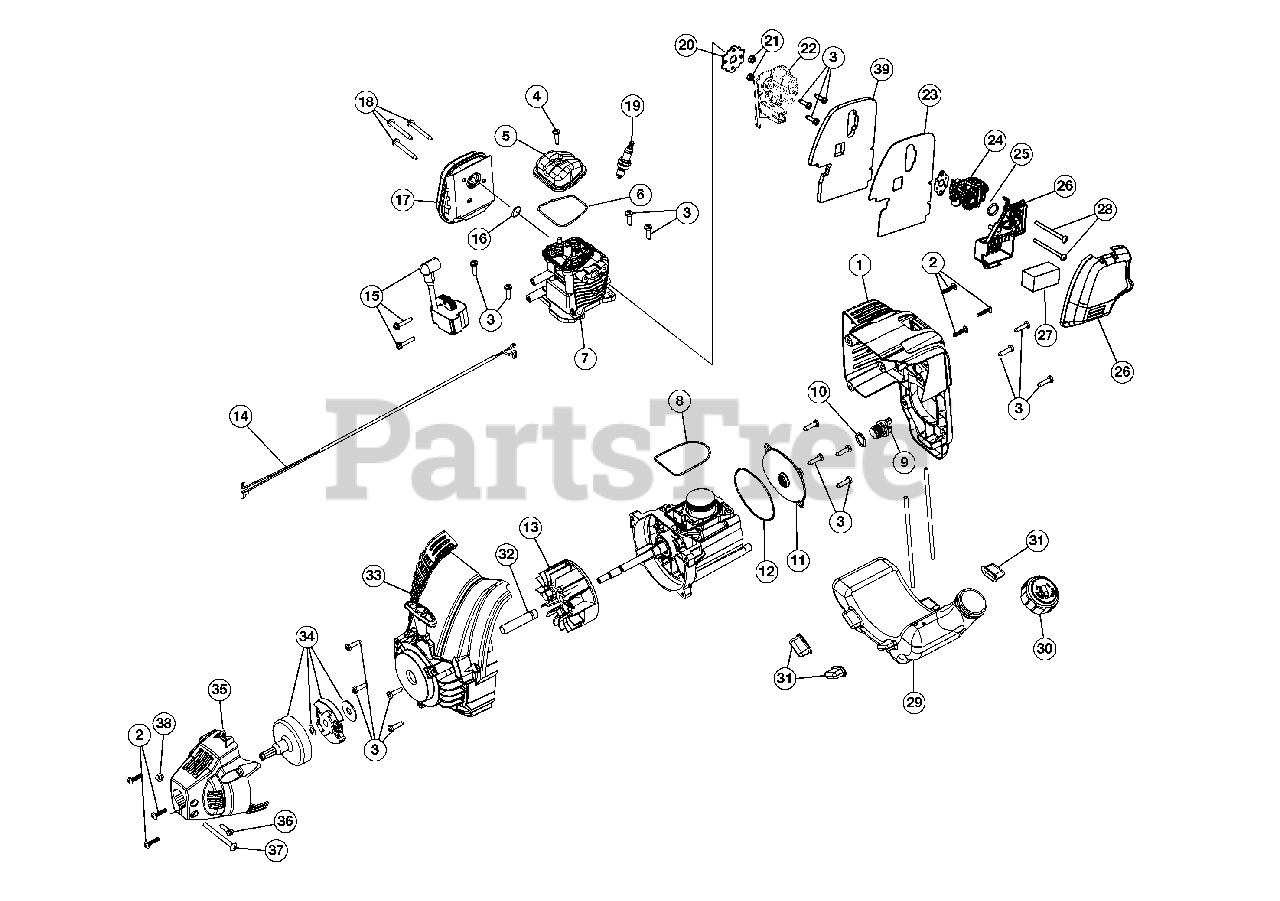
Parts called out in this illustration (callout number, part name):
1	Engine Cover Assembly (Incl. 2 & 3)
2	Cover Screw
3	Housing Screw
4	Rocker Cover Screw
5	Rocker Cover
6	Rocker Cover O-Ring
7	Cylinder Assembly (Incl. 3 - 6 & 8)
8	Cylinder O-Ring
9	Oil Plug (Incl. 10)
10	Oil Plug O-Ring
11	Crankcase Cover
12	Crankcase Cover O-Ring
13	Flywheel Assembly
14	Lead Wires
15	Module Assembly
16	Muffler Gasket
17	Muffler Assembly (Incl. 16 & 18)
18	Muffler Screw
19	Spark Plug
20	Insulator Gasket
23	Carburetor Gasket
24	Carburetor
26	Air Cleaner Cover Assembly (Incl. 27)
27	Air Filter
29	Fuel Tank Assembly w/Fuel Lines (Incl. 30)
31	Fuel Tank Pads
33	Starter Housing Assembly (Incl. 3)
34	Clutch Assembly
35	Clutch Cover (Incl. 2)
36	Anti-Rotation Screw
37	Clamp Screw
39	Heatshield Carb.
